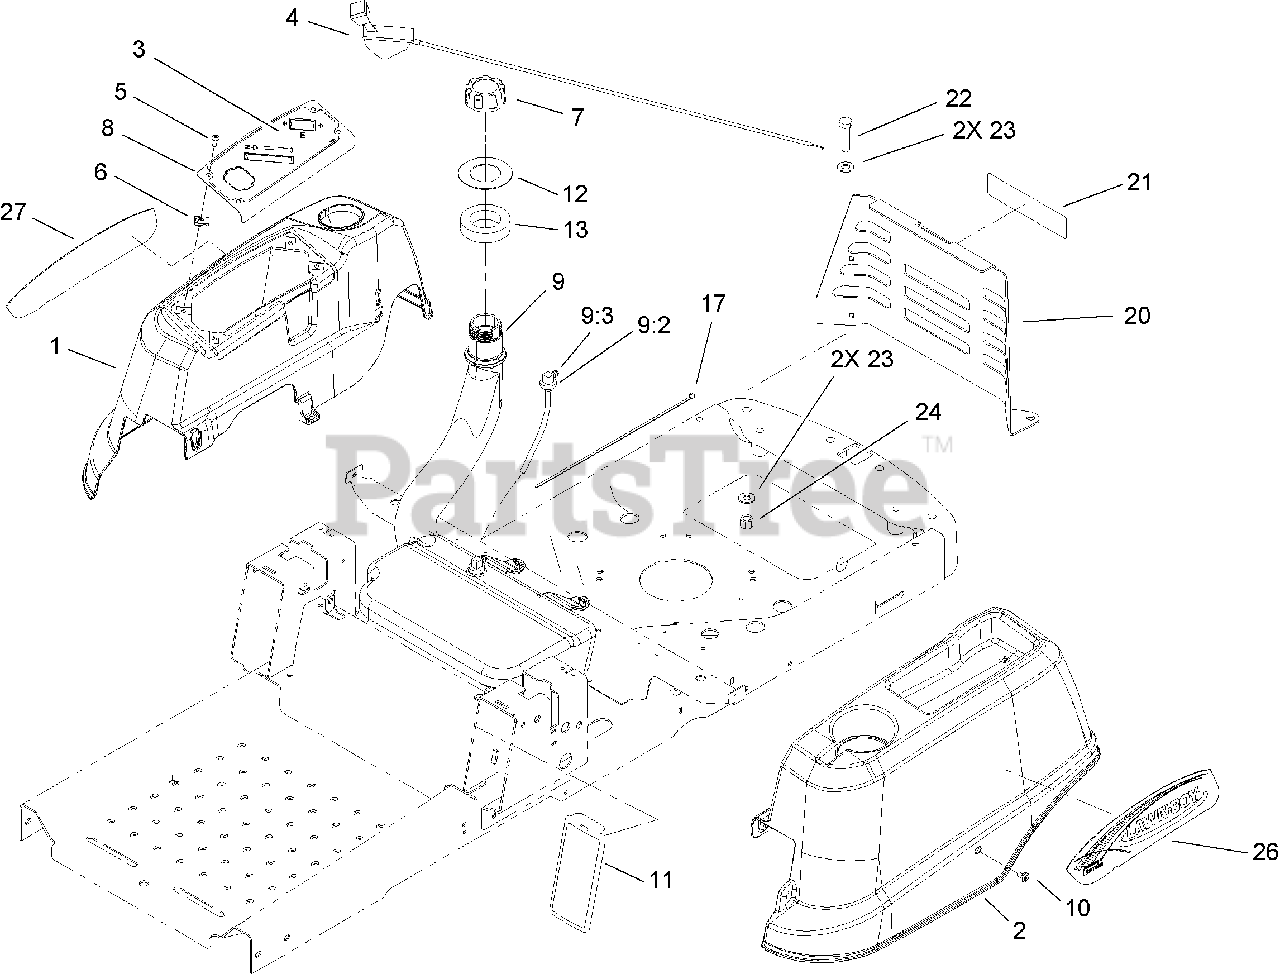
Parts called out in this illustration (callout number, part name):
3	DECAL-PANEL, CONTROL
4	CABLE-THROTTLE
5	SCREW-PRH
7	GAS CAP ASM
8	PANEL-CONTROL
9	FUEL TANK ASM
9:3	FITTING-90 DEGREE
10	SCREW-SHOULDER
11	COVER-CONTROL
12	WASHER-RUBBER
13	SEAL-FOAM
17	TIE-CABLE
20	SUPPORT-COVER, REAR
22	SCREW-HH
23	WASHER-FLAT
24	NUT-LOCK, NI
26	DECAL-POD, RH
27	DECAL-POD, LH
